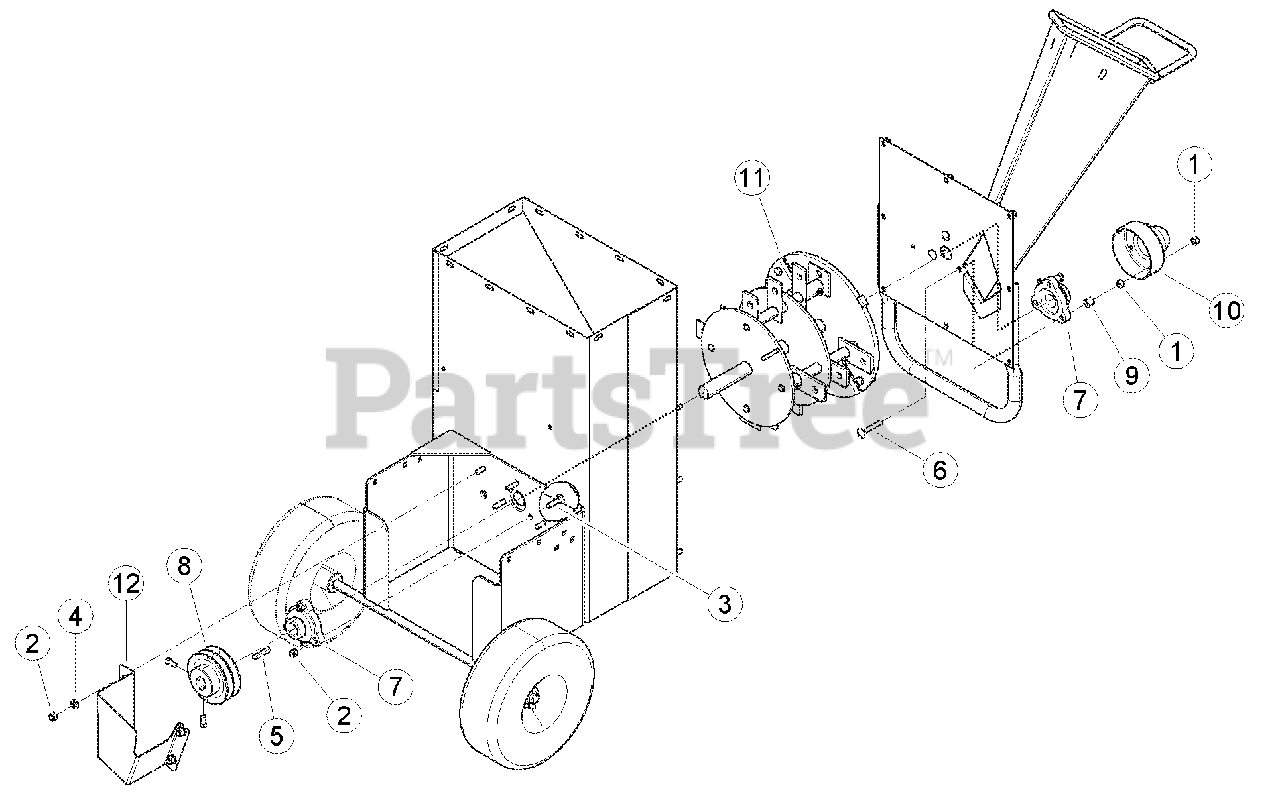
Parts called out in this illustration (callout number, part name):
1	NUT, 5/16 CENTERLOCK NC ZP
2	NUT, 5/16 NE NYLOCK ZP
3	BOLT, 5/16 X 1-1/4 CRG GR5 ZP
4	WASHER, 5/16 SAE FLAT ZP
5	KEY, 1/4 SQUARE X 1-1/2 LONG PLAIN
6	BOLT, 5/16 X 2 CRG GR5 NC ZP
7	BEARING, 1" FLUSHMOUNT CAST W/COLLAR
8	PULLEY, 4X1 2A GROOVE
9	SPACER, .54OD X .50" LG
10	CAP, ROTOR SHAFT END CAP
11	ASSEMBLY, BALANCED ROTOR
12	SHIELD, LOWER
